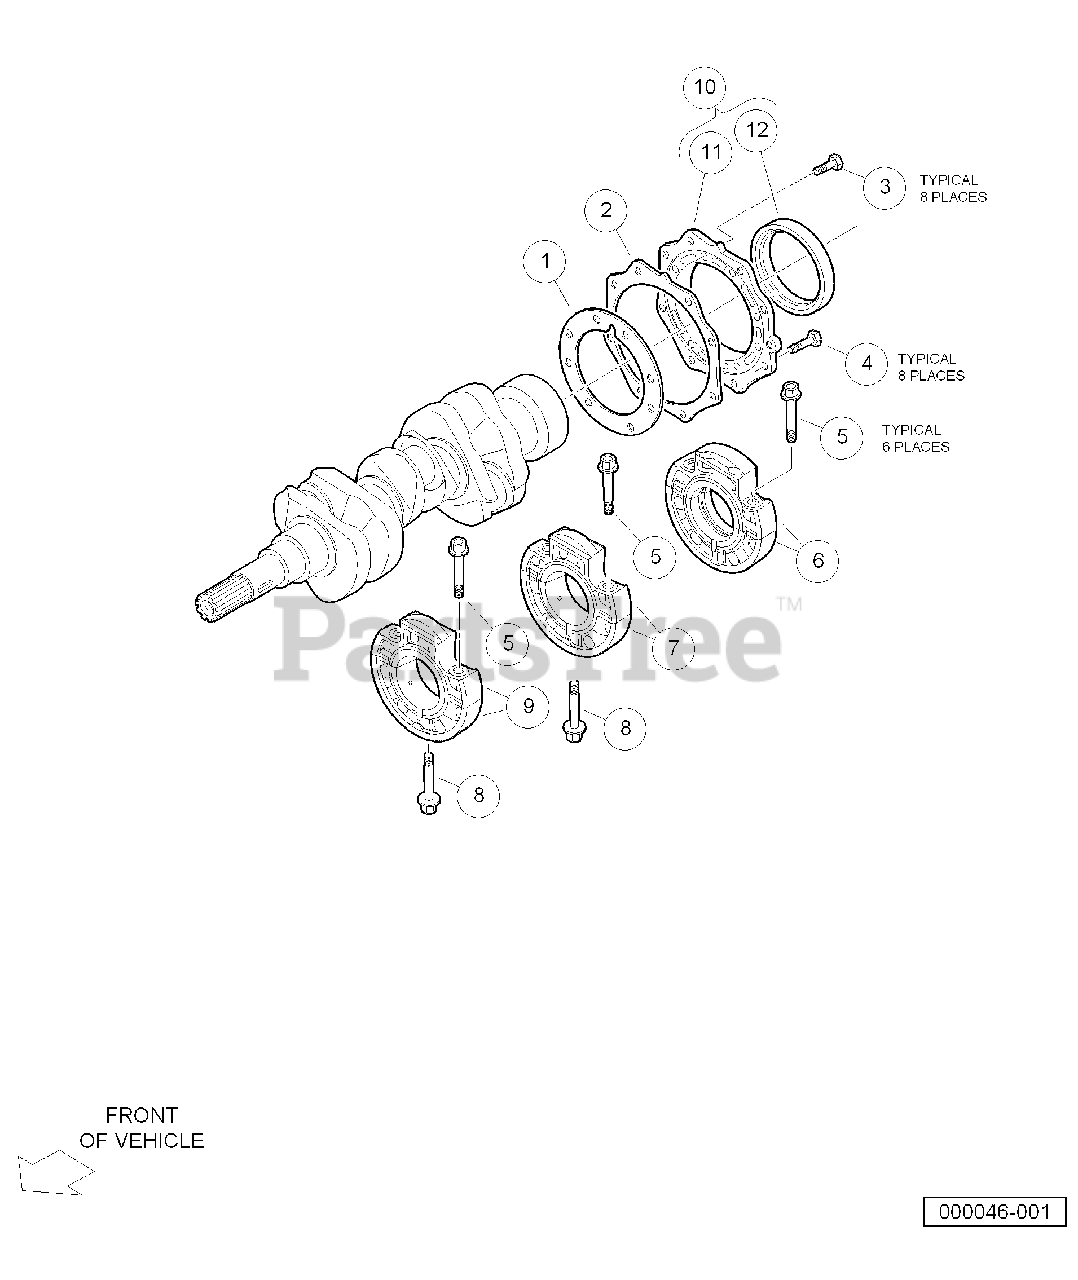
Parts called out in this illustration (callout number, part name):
1	Gasket, Bearing Case
2	Gasket, Cover
3	Bolt, M6 X 1 X 20
4	Bolt, M6 X 1 X 22
5	Bolt, Bearing Case, Top
6	Assy Case, Main Brg, First
7	Assy Case, Main Brg, Sec
8	Bolt, Bearing Case, Bottom
9	Assy Case, Main Brg, Third
10	Assy, Cover, Bearing Case
11	Cover, Bearing Case
